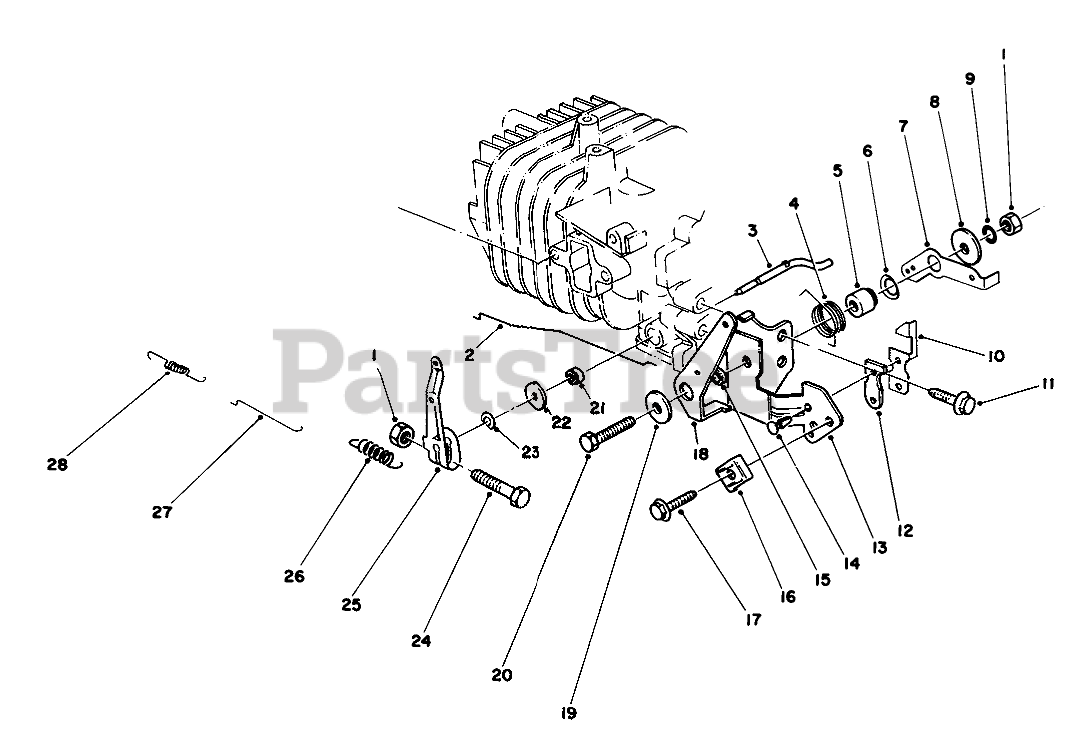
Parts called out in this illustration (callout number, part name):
2	CHOKE ROD
3	Shaft-Govemor
4	SPRING-CHOKE LEVER
5	Gov Lever Spacer
6	Washer-Gov. Spring Lever
7	Lever-Governor Spring (used on units with Serial No. 6000101-6002200)
7	Lever-Governor Spring (used on units with Serial No. 6002201 & up)
8	WASHER
9	LOCKWASHER
10	TERMINAL-KILL SWITCH
11	Bolt-Self Tapping (15mm Lg.)
12	INSULATOR-KILL SWITCH
13	BRACKET-THROTTLE, CONTROL
14	KILL SWITCH RIVET
15	SPACER-CHOKE LEVER
16	CLAMP
18	LEVER-CONTROL, CHOKE
19	WASHER
21	SEAL-OIL
22	WASHER
23	E-RING
24	Bolt-Governor Arm (used on units with Serial No. 6000101-6002200)
25	Arm-Governor (used on units with Serial No. 6000101-6002200)
25	Arm-Governor/Bolt Assy. (used on units with Serial No. 6002201 & up)
26	Spring-Governor (used on units with Serial No. 6000101-6002200)
26	Spring-Governor (used on units with Serial No. 6002201 & up)
27	ROD-CARBURETOR
